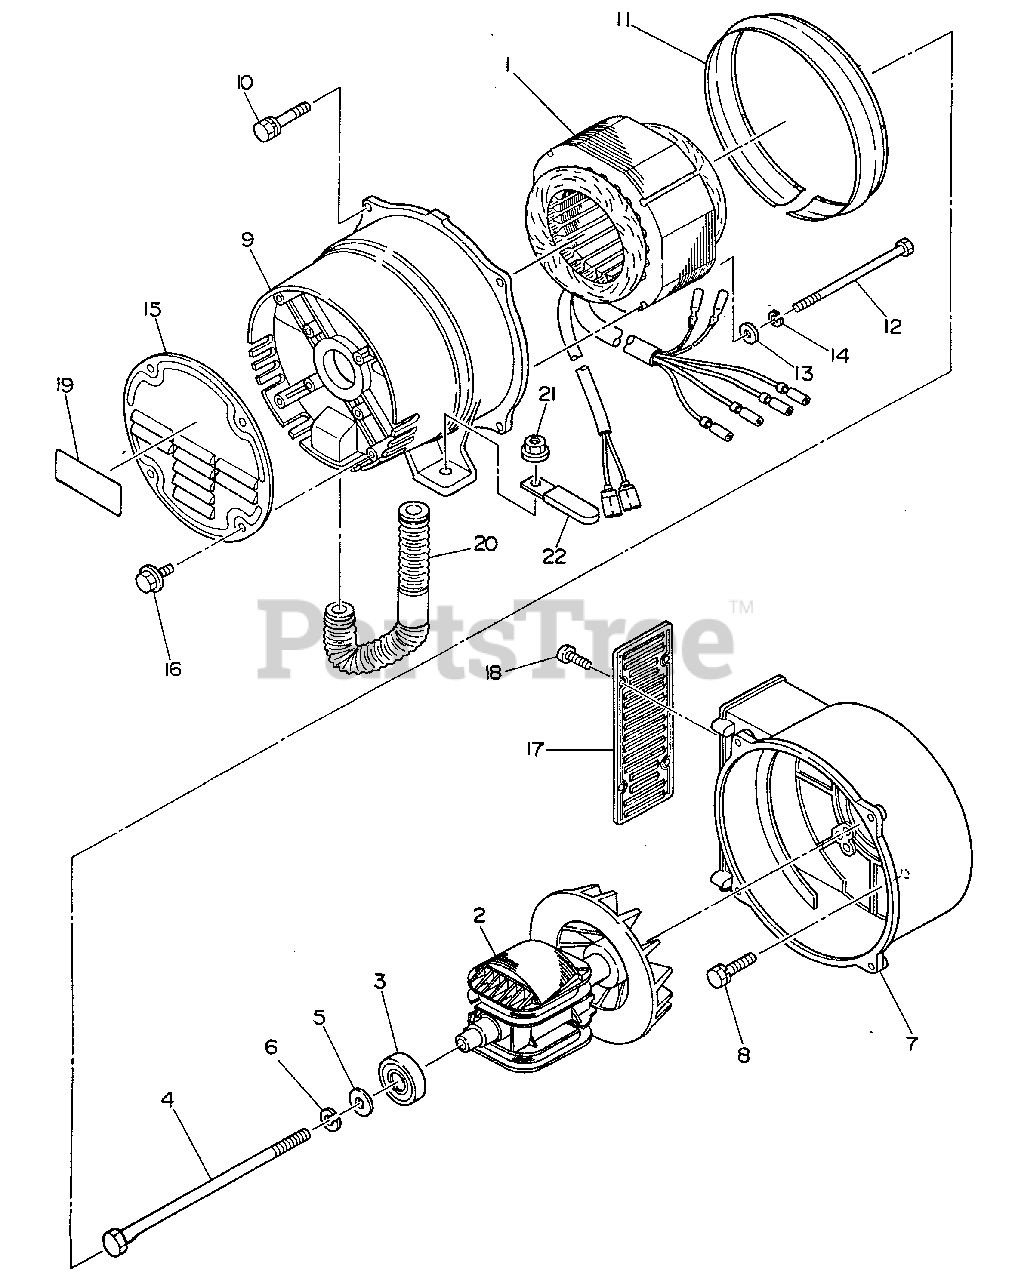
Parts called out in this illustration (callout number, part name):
1	STATOR ASSY
2	ROTOR ASSY
3	BEARING, BALL
4	BOLT
5	WASHER
6	LOCKWASHER
7	COVER - FRONT
8	BOLT
9	COVER ASSY - REAR
10	BOLT
11	SUPPORT RING
13	WASHER
14	LOCKWASHER
15	COVER
16	BOLT - FLANGE
17	PROTECTOR
18	SCREW -- TAPPING
19	LABEL - GENERATOR
20	BUSHING
21	NUT - 8 -- FLANGE
22	CLAMP
